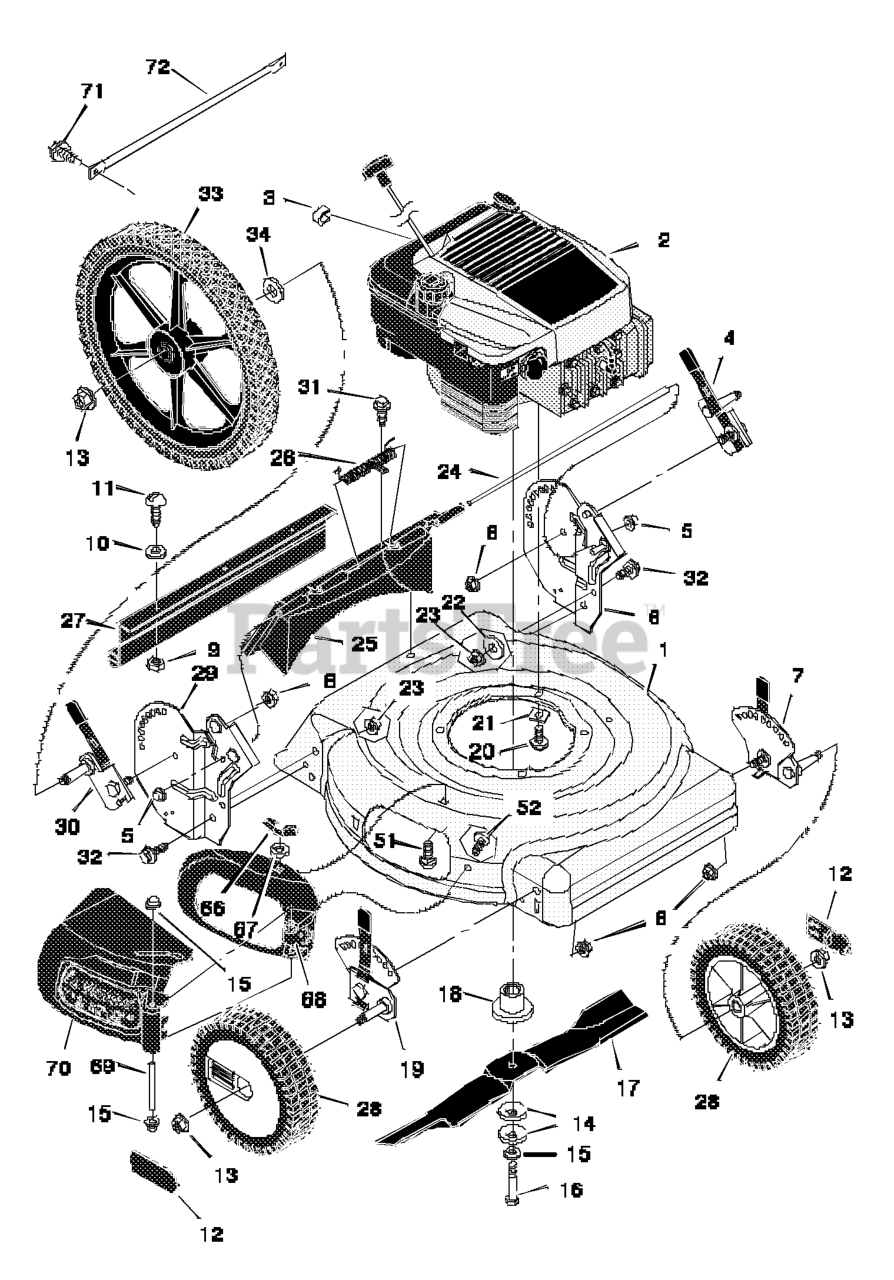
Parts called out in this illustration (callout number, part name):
1	Housing
2	Engine *
3	Stop, Rope (Recoil - Start)
4	Adjuster, Left Height
5	Push On Cap
6	Bracket, Left Handle
7	Adjuster, Left Front Height
8	Nut, Flange
9	Nut, Hex
12	Hub Cap
13	Nut, Flange
14	Washer, Belleville
18	Adapter, Blade
19	Adjuster, Right Front Height
20	Bolt, Engine
21	Support, Engine
22	Washer
23	Nut, Flange
24	Rod, Pivot
25	Door, Rear
27	Guard, Rear
28	WHEEL & TIRE ASSEMBLY, White, 8"
29	Bracket, Right Handle
30	Adjuster, Right Height
32	Bolt
33	WHEEL & TIRE ASSEMBLY, Ball Bearing, 14"
51	Bolt, Carriage
66	Wingnut
67	Retainer, Push
69	Pin, Pivot
70	Deflector, Chute
